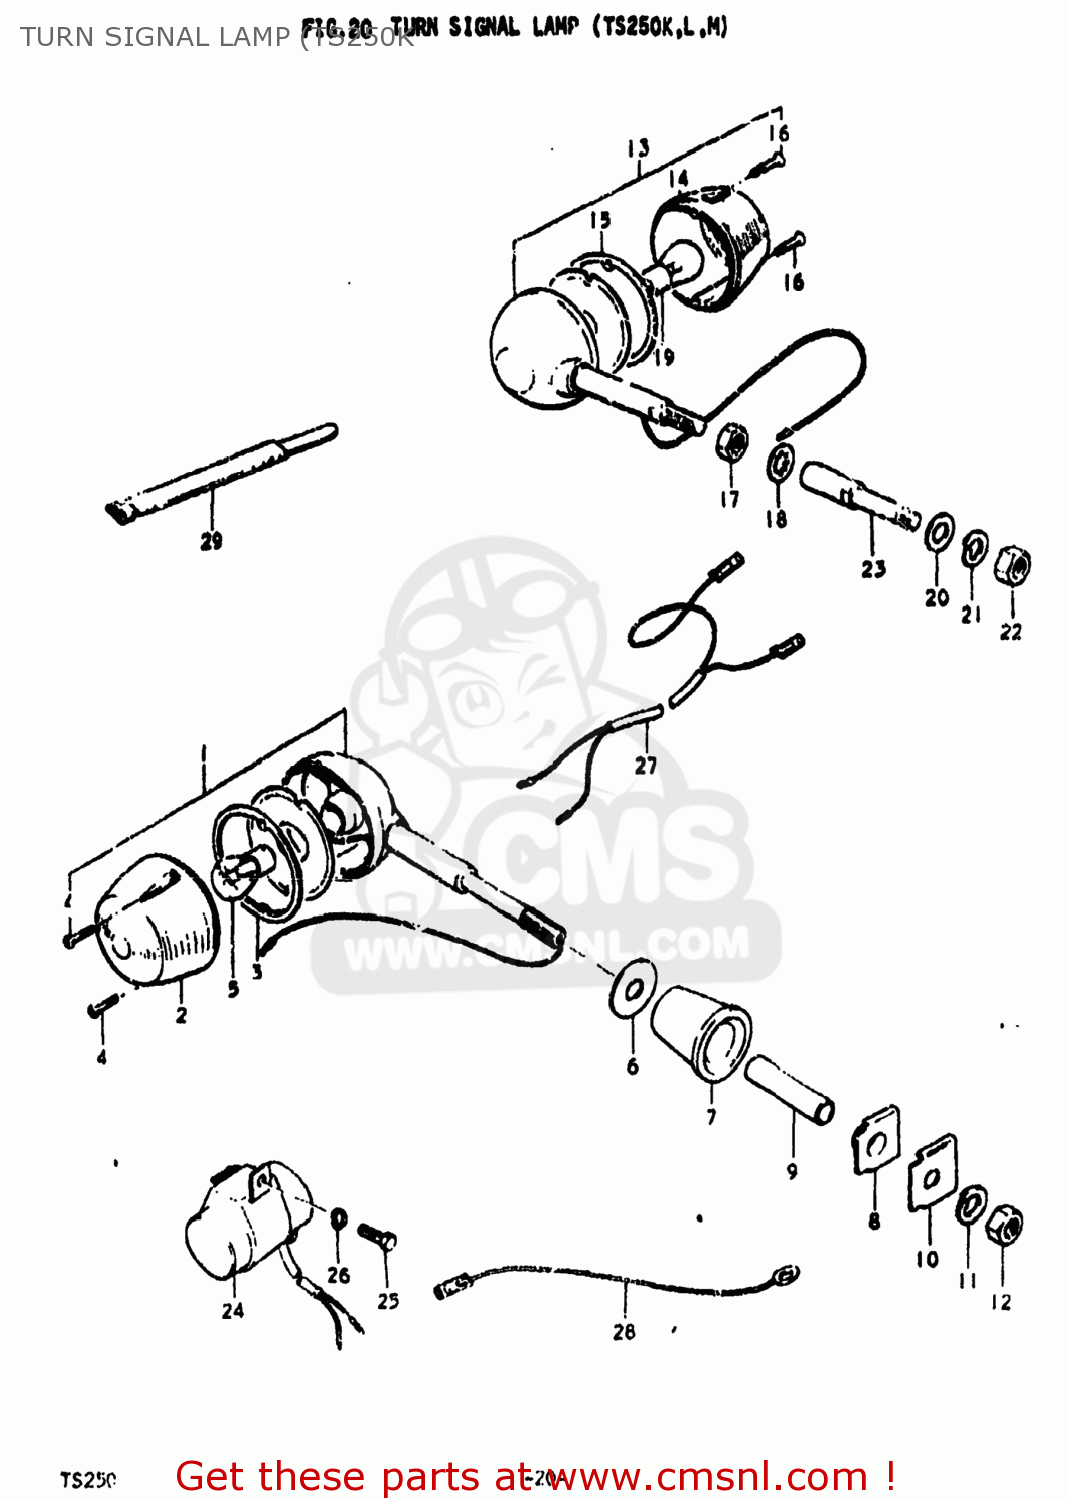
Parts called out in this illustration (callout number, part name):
1	LAMP ASSEMBLY,FRONT TURN SIGNAL
2	LENS,TURNSIGNAL
3	GASKET,TURNSIGNAL LENS (NAS)
4	SCREW
5	BULB(6V17W,STANLEY,A4513A)
6	WASHER(10.5X20X3.2)
7	CUSHION
8	CUSHION,FRONT TURNSIGNAL
9	SPACER, TURN SIGNAL
10	PLATE, TURN SIGNAL
11	LOCK WASHER
12	NUT
13	LAMP ASSY,RR TURNSIGNAL
14	LENS,TURNSIGNAL
15	GASKET,TURNSIGNAL LENS (NAS)
16	SCREW
17	NUT
19	BULB(6V17W,STANLEY,A4513A)
20	WASHER
21	LOCK WASHER
22	NUT
23	STAY,TURN SIGNAL,REAR
24	RELAY,TURN SIGNAL
25	BOLT
26	LOCK WASHER
27	WIRE
28	WIRE
29	CLAMP
